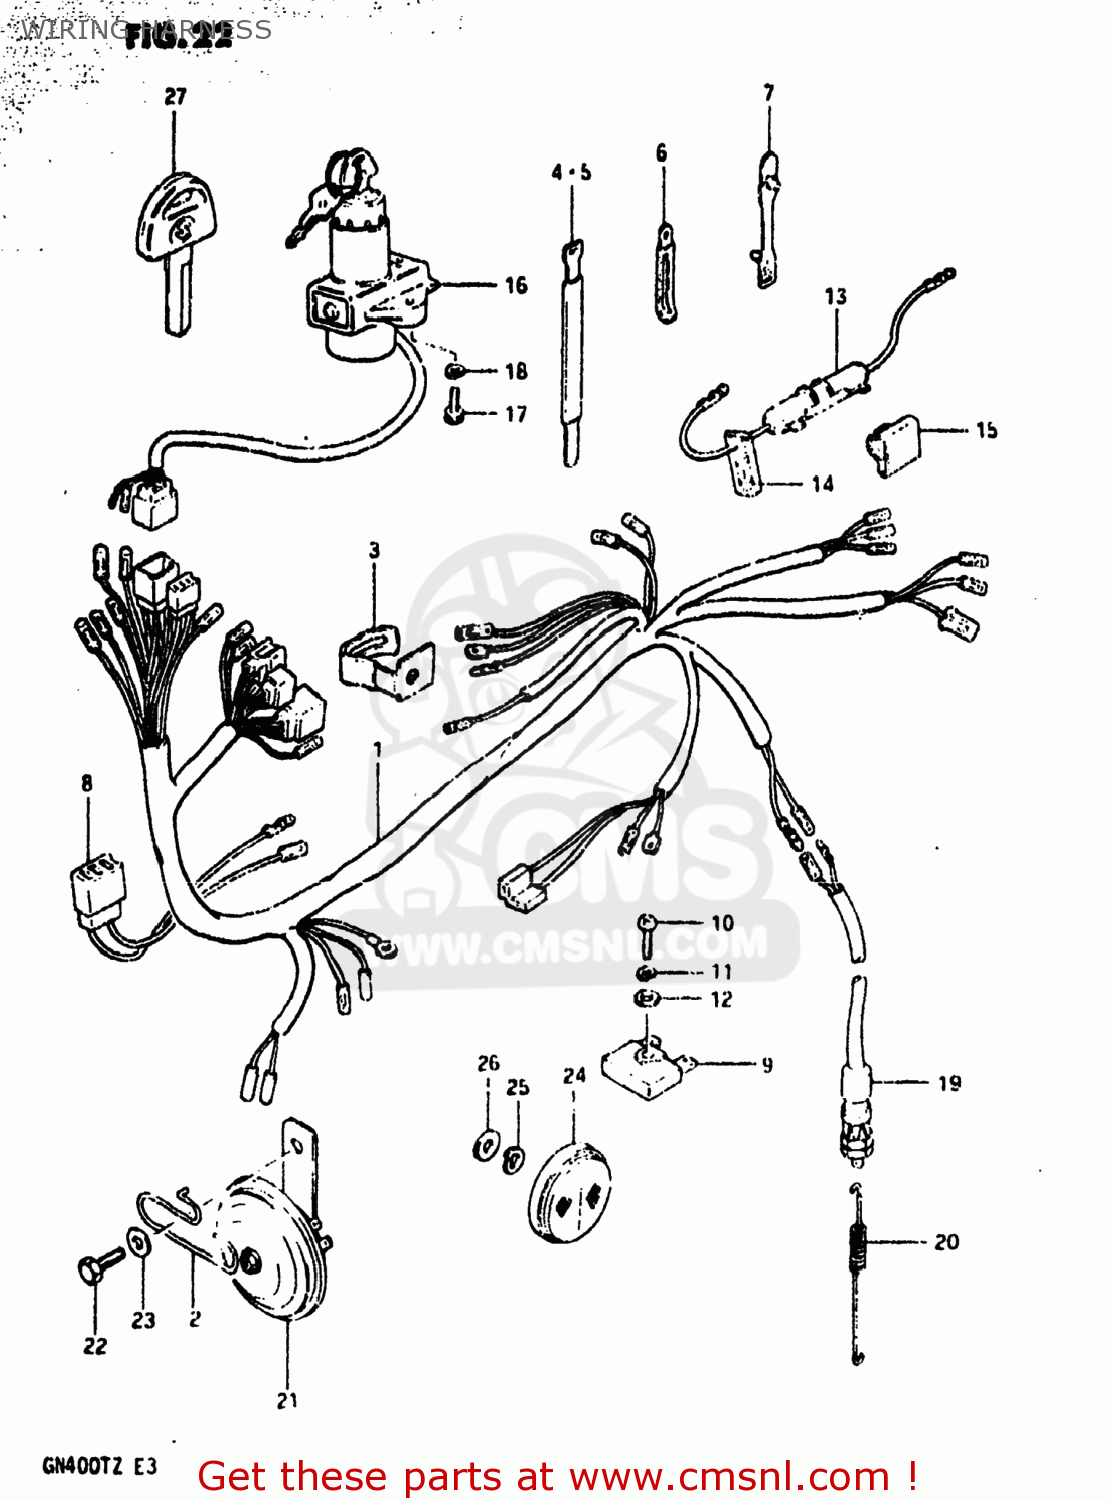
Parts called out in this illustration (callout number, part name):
1	HARNESS,WIRING
2	CLAMP,WIRING HARNESS
3	CLAMP,WIRING HARNESS
4	CLAMP
5	CLAMP
6	CLAMP
7	CLAMP,L:88
8	WIRE,DC LIGHTING
9	RECTIFIER ASSEMBLY
10	SCREW 5X20
11	LOCK WASHER
12	WASHER
13	BOX ASSEMBLY,FUSE
14	FUSE(15A)
15	HOLDER,FUSE CASE
16	IGNITION SWITCH/STEERING LOCK
17	BOLT
18	LOCK WASHER
19	SWITCH ASSEMBLY,STOP LAMP
20	SPRING
21	HORN ASSEMBLY
22	BOLT
23	WASHER
24	REFLEX REFLECTOR,RR
25	LOCK WASHER
26	WASHER
27	KEY,BLANK
